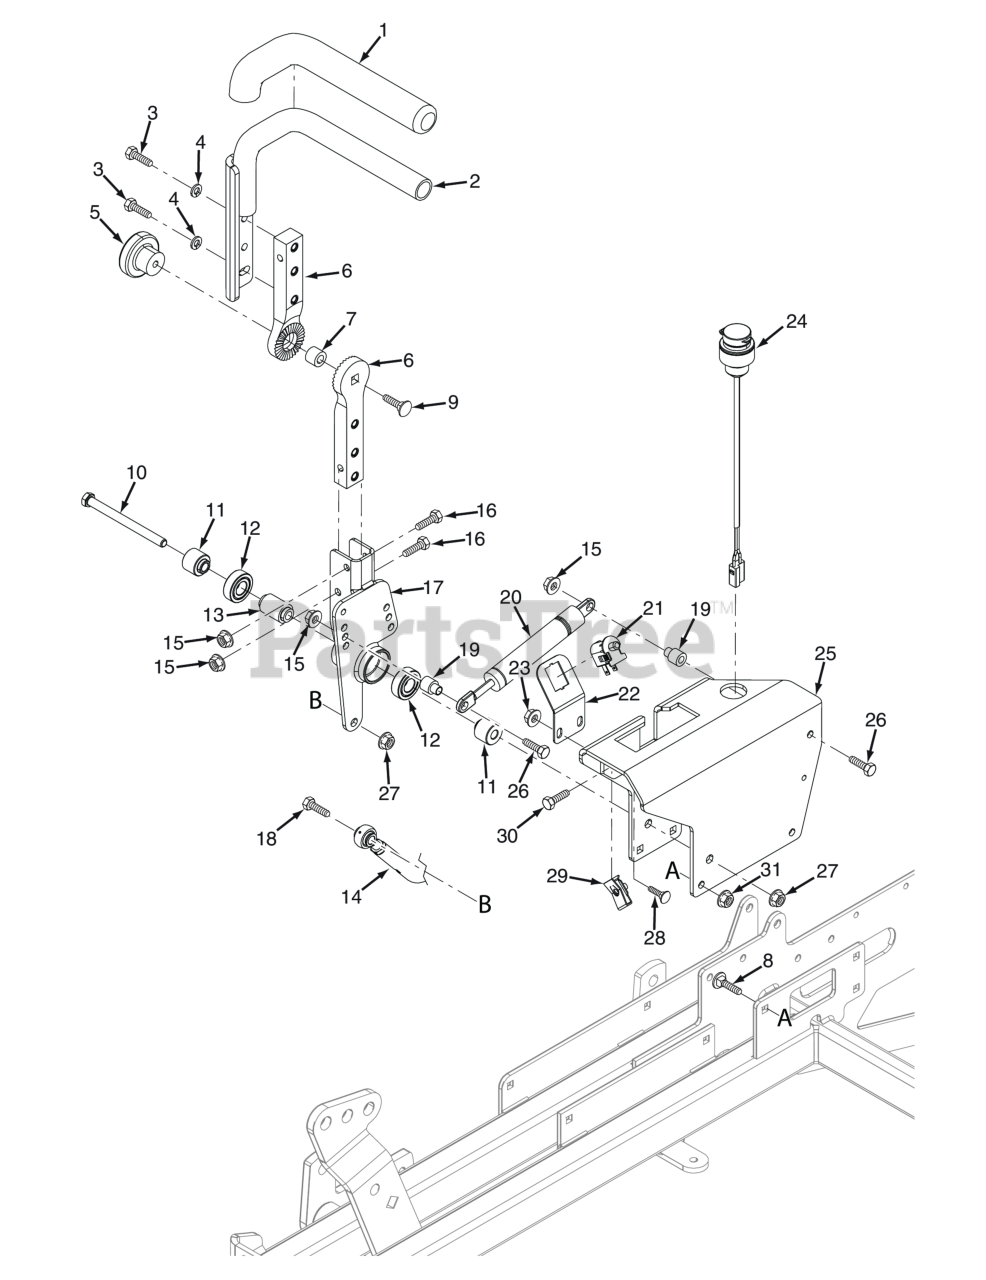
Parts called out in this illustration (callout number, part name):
1	Grip, Control Handle
2	Handle Bar w/Grip - RH
3	Bolt, Heax Head 5/16-18 x 1" (48V / 52V)
4	Lockwasher, 5/16 (.317 x .586 x .078) Helical Spring
5	Knob, Control Handle
6	Pivot, Control Lever
7	Spacer, Rubber
8	Bolt, 5/16-18 x .75 RHSN Carriage
9	Bolt, RDHD Carr. 3/8-16 x 1-1/2 (52" & 61")
10	Bolt, 3/8 - 16 x 4 - 1/2" Hex Head
11	Spacer, Controls
12	BEARINGS, BALL, NEUTRAL RETURN
13	Spacer, Bearing
14	Steering Link Assembly, SCZII
15	HEX NUT, ELASTIC STOP LOCK, 5/16-18
16	Bolt, Hex Head 5/16-18 x 1-1/2" - Front
17	Pivot Weldment, Control Arm RH
18	Bolt, Hex Head 3/8-16 x 1-1/2" B&S 32BV
19	Spacer, Pump Dampener
20	Damper, Steering
21	Switch, Interlock, Normally Open
22	Bracket, Operator Presence Switch
23	Nut, Flanged Elastic Stop 1/4-20
24	Power Plug, 12V
25	Control Plate w/ Decals RH
26	Bolt, Hex Head 5/16-18 x 1-1/2" (Right Front Engine Mounting, Briggs and Kohler Only)
27	HEX NUT, ELASTIC STOP LOCK, 3/8-16
28	Serr. Fl. Hex Head CPSCR, 1/4-20 x 3/4"
29	U-Nut, 3/8-16 (short)
30	Bolt, Hex Head 3/8-16 x 1-1/4" with Thread Lock Patch
31	Nut, Serrated Flange 5/16-18 (Right Front Engine Mounting, Briggs and Kohler Only)
